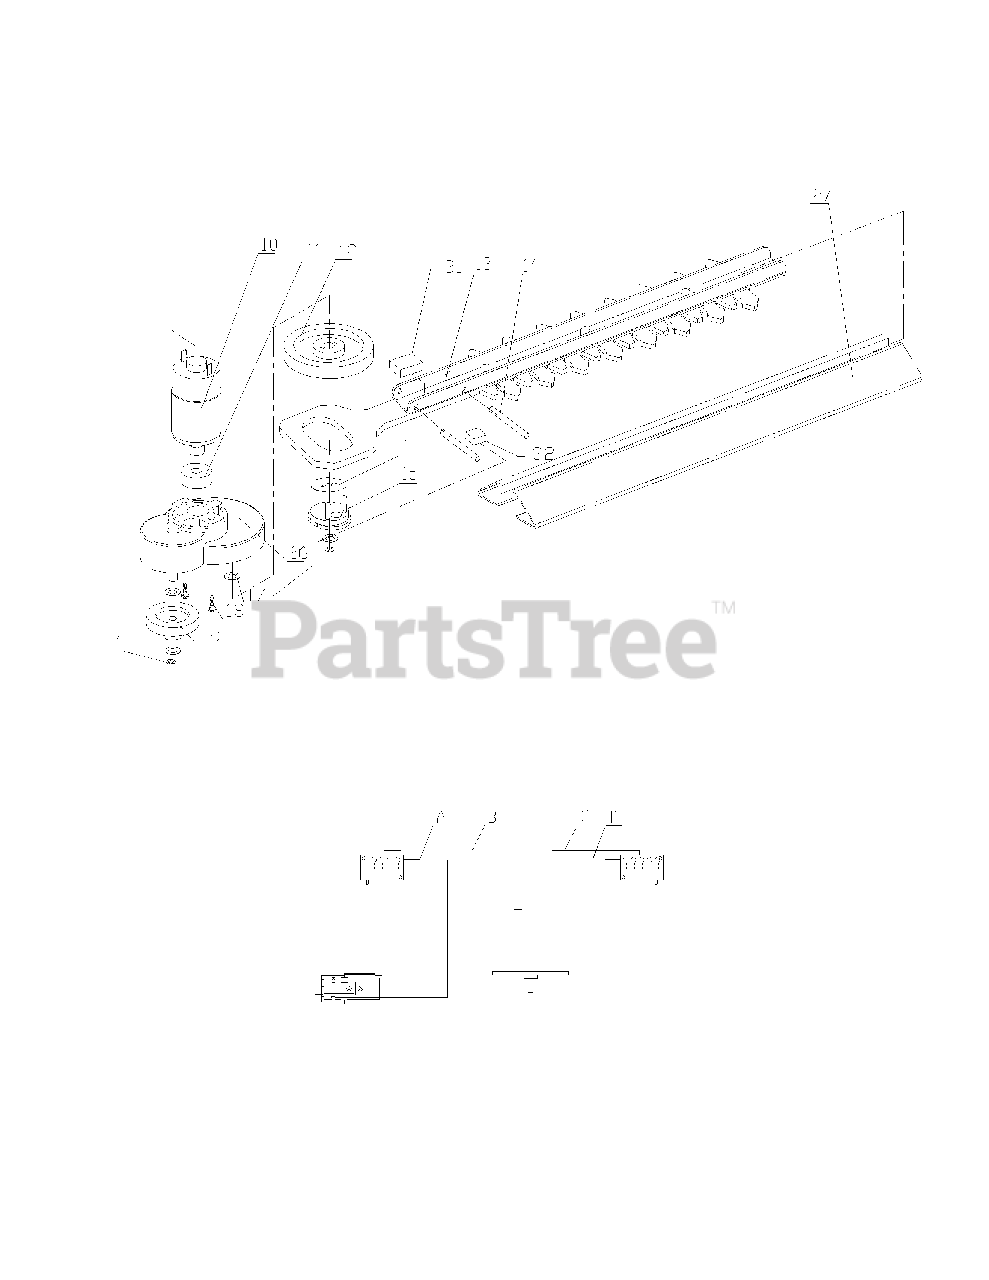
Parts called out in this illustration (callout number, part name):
4	C RING
6	HOUSING (L)
11	MOTOR GEAR
12	LARGE GEAR
15	FIXED BLOCK
19	MIDDLE GEAR
20	HOUSING (R)
25	TERMINAL HOLDER
26	1.9 Ah BYD BATTERY ASS'Y
27	BLADE CONER
